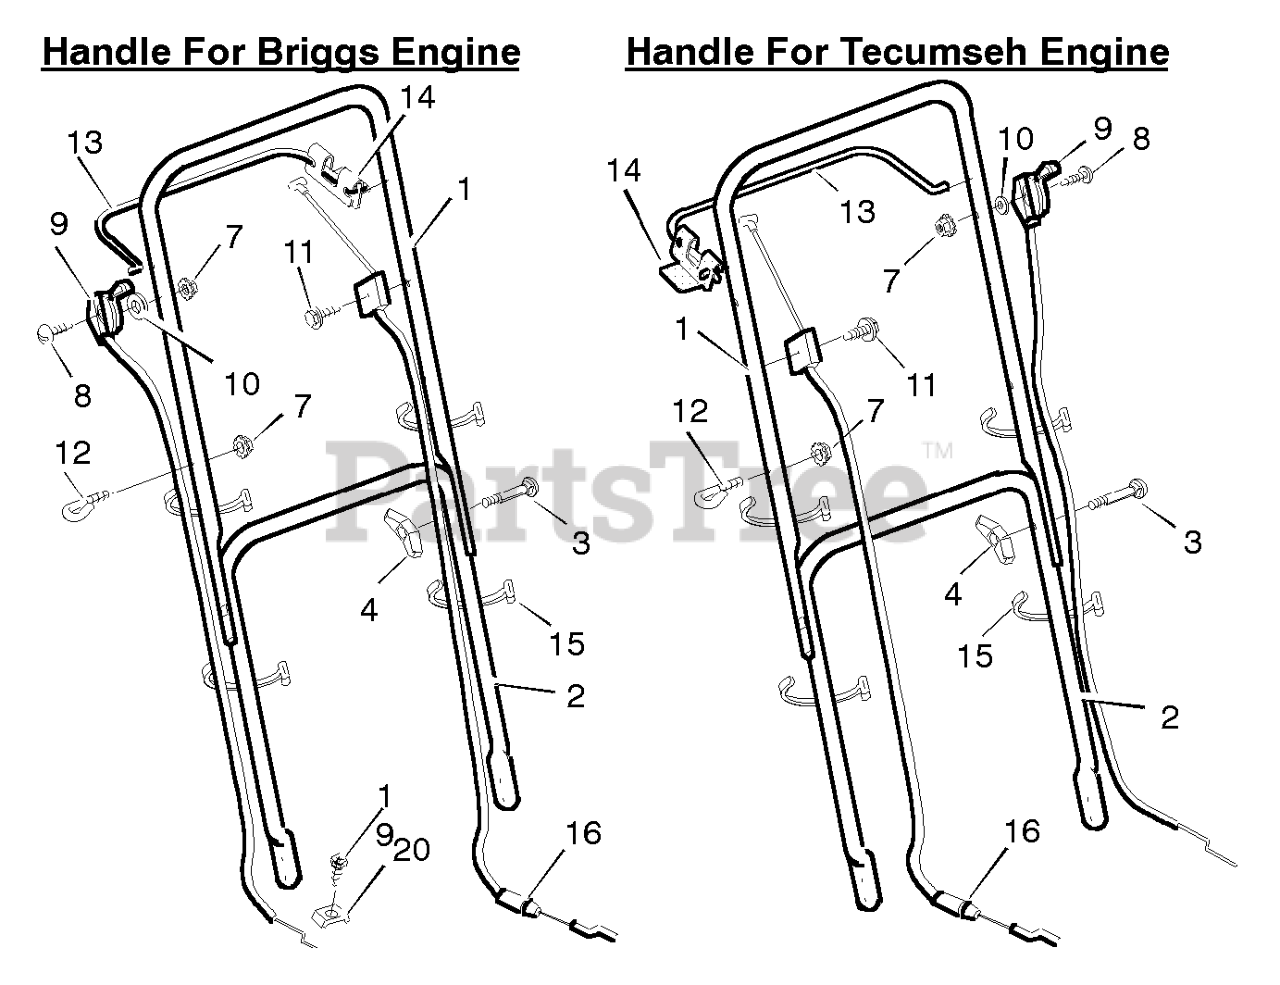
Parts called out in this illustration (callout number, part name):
1	Handle, Upper (Black)
2	Handle, Lower (Black)
4	Knob, Plastic
7	Locknut
9	Throttle Control
10	Washer
12	GUIDE, ROPE
13	Engine Stop Lever
14	Bracket, Stop Lever
15	Fastener, Cable
16	Engine Stop Cable *
19	Screw *
20	Clamp
